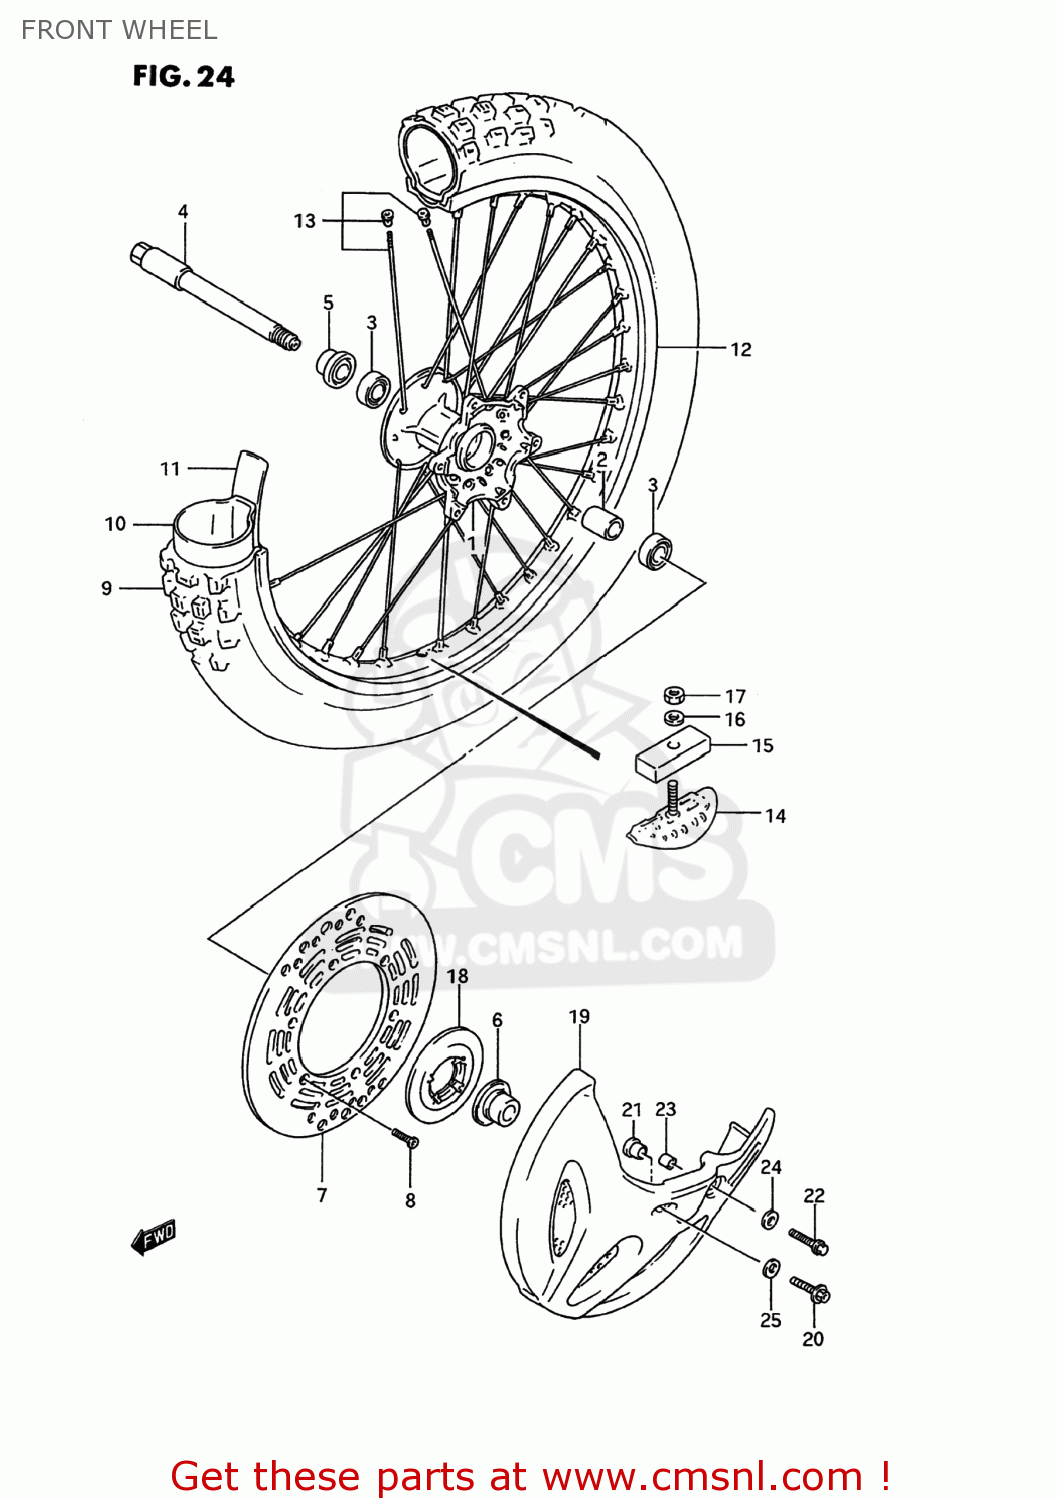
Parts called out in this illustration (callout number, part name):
1	HUB,FRONT
2	SPACER,FRONT HUB BEARING
3	BEARING
4	AXLE,FR
5	SPACER,FR AXLE,R
6	SPACER,FRONT AXLE,LEFT
7	DISC,FR BRAKE
8	SCREW,BRAKE DISC
9	TIRE,FRONT
10	TUBE
11	PROTECTOR,WHEEL INNER
12	RIM,FRONT WHEEL (1.60X2
13	SPOKE SET,FR WHEEL
14	STOPPER,BEAD
15	CUSHION,BEAD STOPPER
16	WASHER
17	NUT
18	CAP,FR HUB,L
19	COVER,FR BRAKE DISC
20	BOLT
21	WASHER (8.5X16X1.6)
22	BOLT
23	SPACER(6.1X8X14.5)
24	WASHER(6.5X18X1)
25	WASHER(8.5X18X1)
